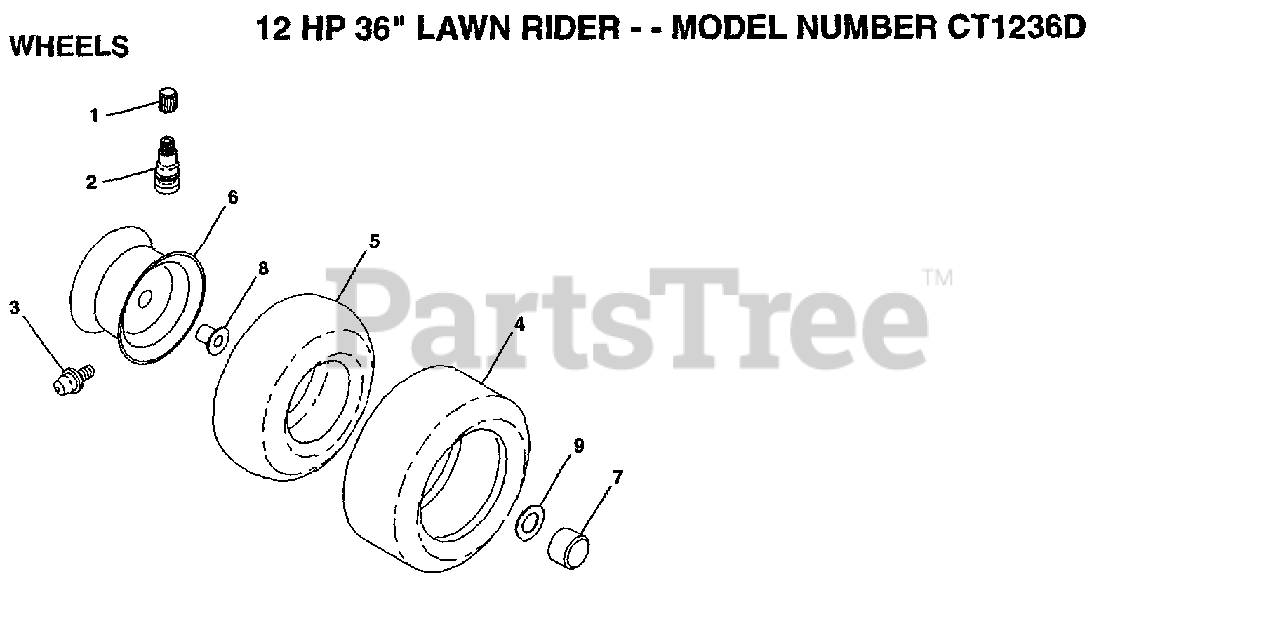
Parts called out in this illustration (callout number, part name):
1	VALVE CAP
2	VALVE STEM LT
3	FITTING LT
5	TUBE.5.3/4.5/6
7	HUB CAP
8	"FLANGE, BEARING"
9	WASHER
